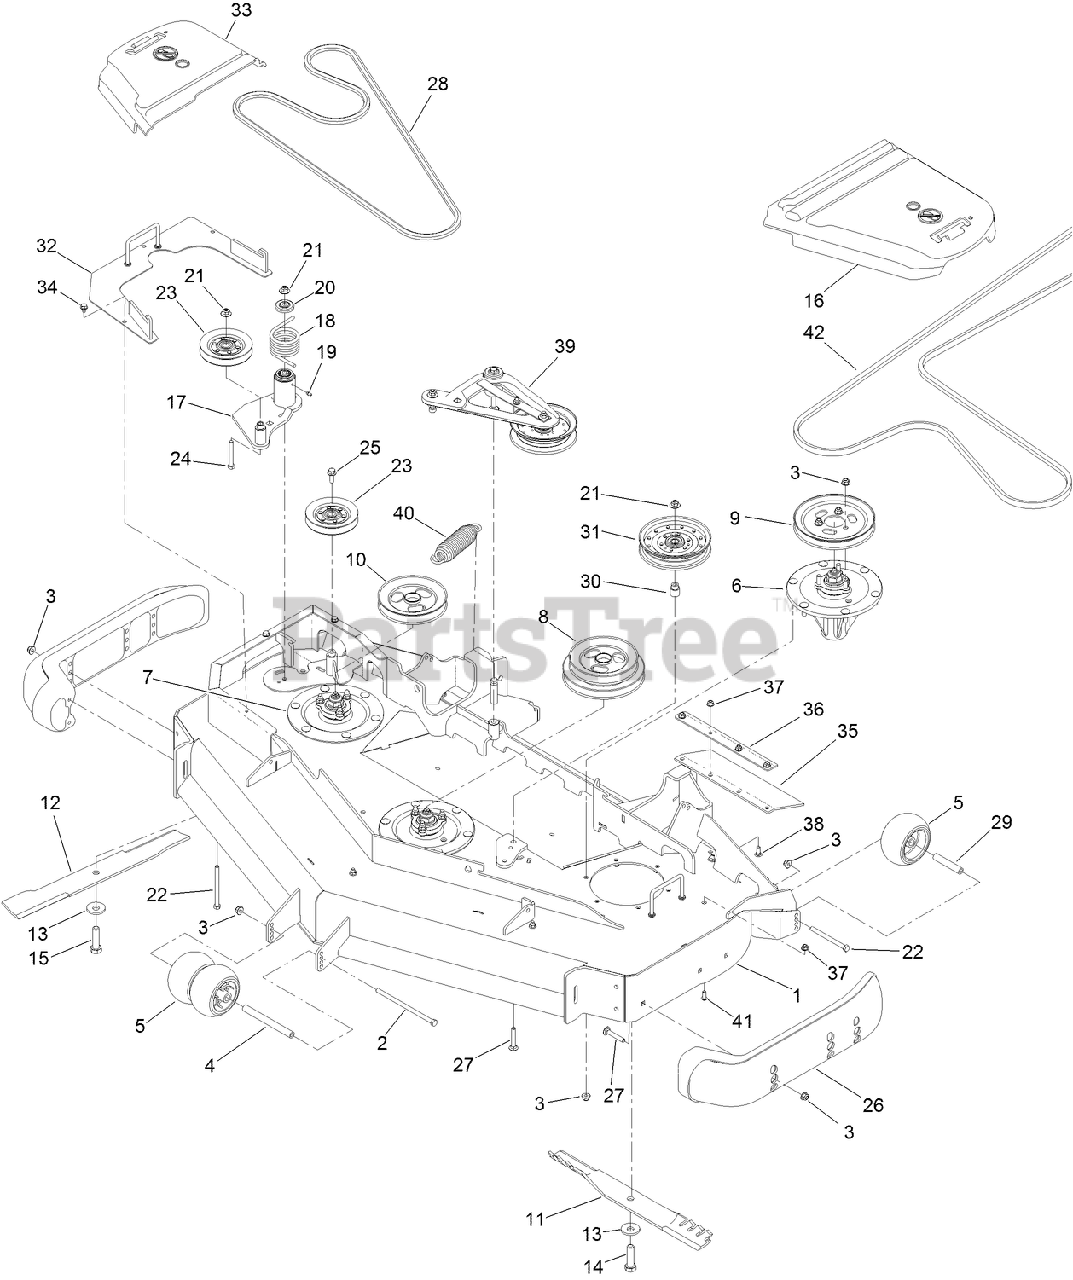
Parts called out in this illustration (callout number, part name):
1	DECK DECAL ASM
2	SCREW-HH
3	NUT-HF, NI
4	SPACER-WHEEL
5	ROLLER-SCALP, ANTI
6	SPINDLE ASM
7	LH SPINDLE ASM
8	PULLEY
9	Pulley
10	PULLEY
11	BLADE-ATOMIC, 20.5IN
12	BLADE-ROTARY, 20.5IN LOW FLOW
13	Washer-Blade Bolt, Heavy
14	SCREW-BLADE
15	SCREW-BLADE, LH
16	COVER-BELT, LH
17	IDLER ASM
18	SPRING-TORSION
19	FITTING-GREASE
20	GUARD-TOP
21	NUT-FLANGE, NI
22	SCREW-HH
23	SHEAVE
24	SCREW-HH
25	SCREW-HHF
26	SKID-BUMPER, DECK
27	SCREW-CARR
29	TUBE-SPANNER
30	Bushing, Idler
31	PULLEY-IDLER, FLAT
32	COVER-DRIVE REVERSE
33	COVER-BELT, RH
34	SCREW
35	GUARD-TIRE
36	SUPPORT-OUTER FLAP
37	NUT-HF, NI
38	SCREW-CARR
39	DECK IDLER ASM
40	SPRING-EXTENSION
41	SCREW-HSBH
